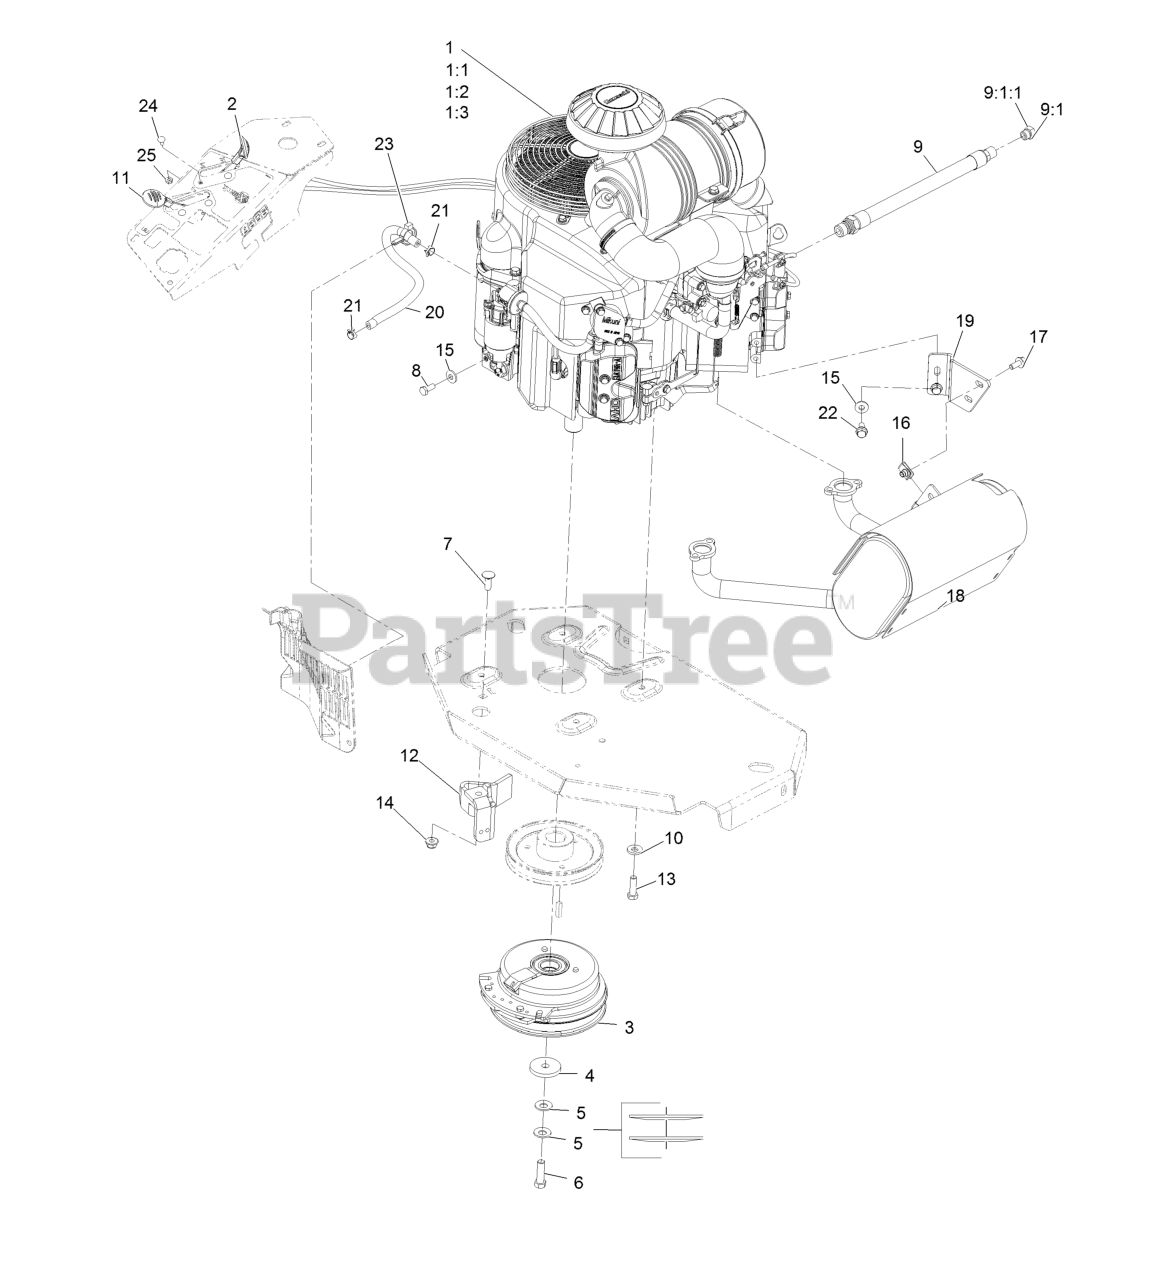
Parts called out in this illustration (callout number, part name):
1:1	Kawasaki 49065-2078 Engine Oil Filter
1:2	Kawasaki 11013-7044 Engine Air Filter
1:3	Kawasaki 11013-7045 Safety Filter
2	ASM, Choke Cable
3	Clutch Kit
4	Washer-Clutch
5	Washer-Spring Disc 7/16
6	Screw-HH 7/16-20 X 1 1/2 W/Loctite
7	Bolt-Carriage 3/8-16 X 1
8	Screw-HH M8-1.25 X 20Mm
9	Asm-Hose Oil Drain W/Plug
9:1	Plug-W/O-Ring
9:1:1	O-Ring
10	Washer-Spring Disc 3/8
11	ASM,Throttle Cable
12	Clutch-Anchor
13	Screw-HH 3/8-16 X 1 1/4
14	Nut-Nyloc 3/8-16 Flg
15	Washer-Spring Disc 5/16
17	Screw-HH Flg 5/16-18 X 3/4
18	Muffler
19	Bracket-Muffler
20	Hose-Fuel Line 15"
21	Clamp-Hose
22	Screw-HH M8-1.25 X 20Mm
23	Clamp-Hose
24	Bolt-Carriage #10-24 X 1/2
25	Nut-Nyloc #10-24
